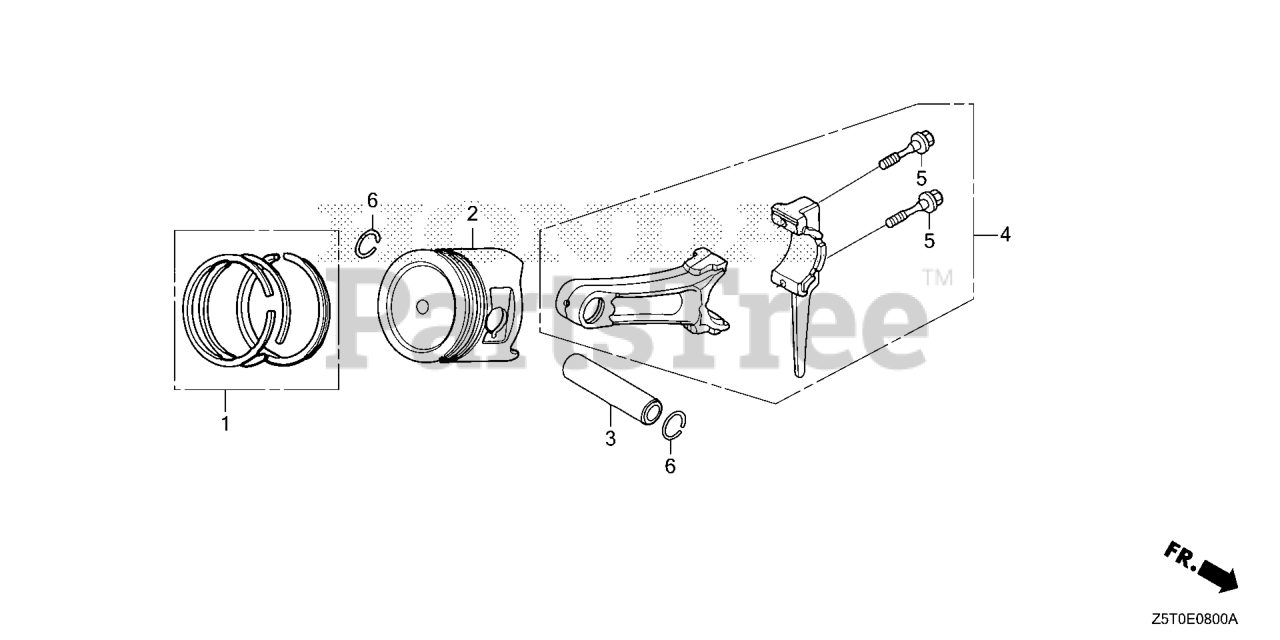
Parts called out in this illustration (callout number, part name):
1	RING SET, PISTON (STD) (TEIKOKU)
2	PISTON (STD)
2	PISTON (0.25)
2	PISTON (0.50)
2	PISTON (0.75)
3	PIN, PISTON
4	ROD ASSY., CONNECTING (0.25 LOWER SIZE)
4	ROD ASSY., CONNECTING (STD)
5	BOLT, CONNECTING ROD
6	CLIP, PISTON PIN (20MM)
